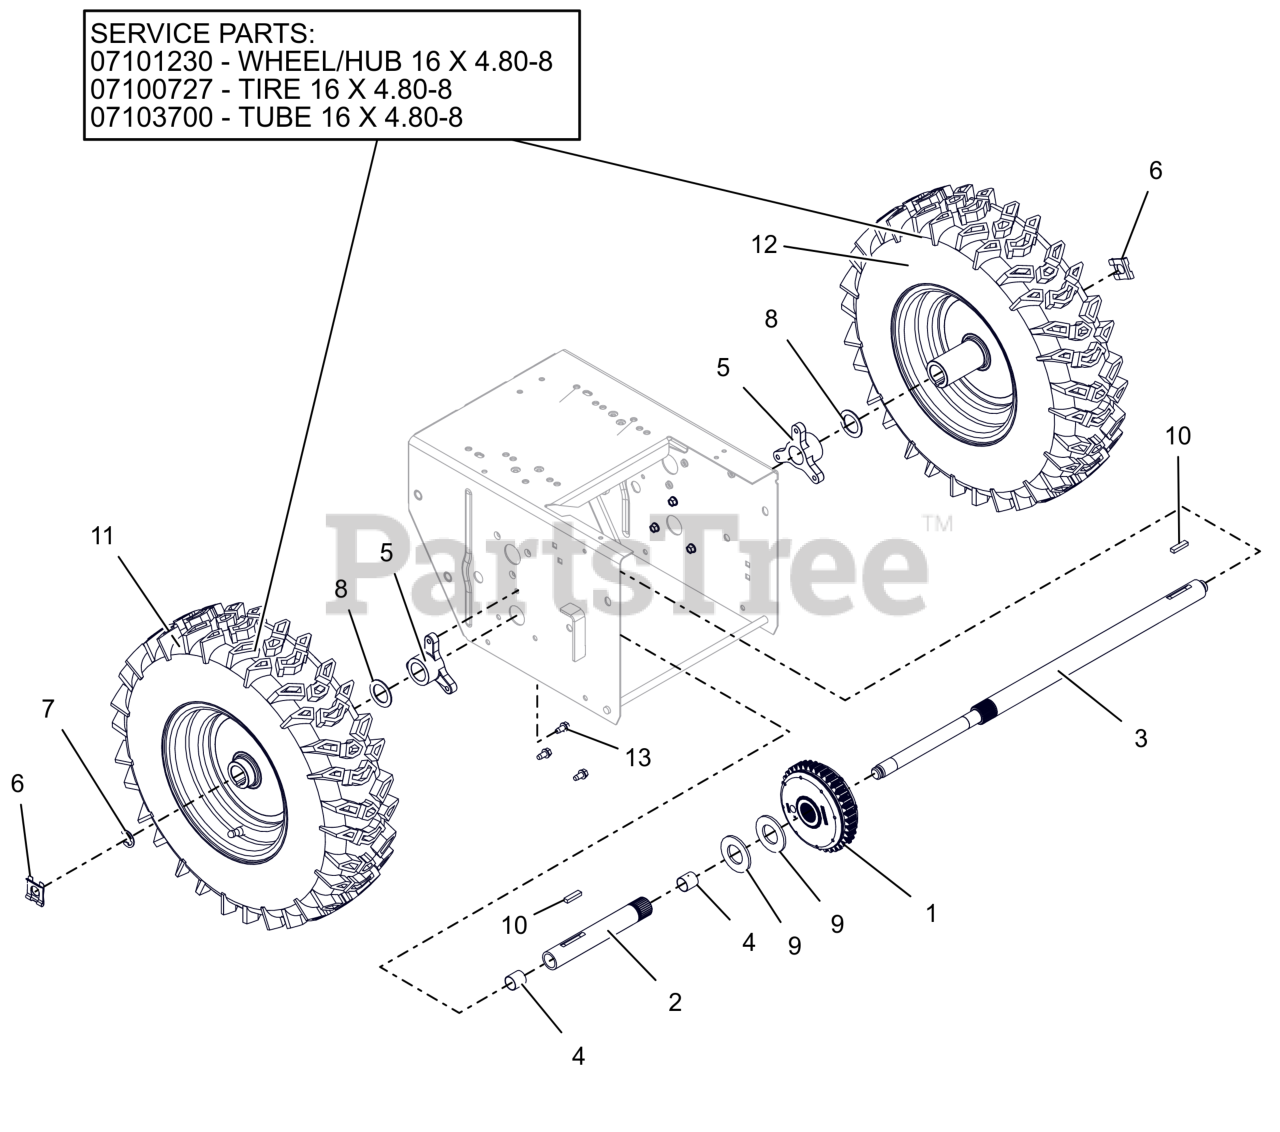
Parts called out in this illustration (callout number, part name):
1	DIFFERENTIAL, AUTOMATIC
2	AXLE, SHORT - W/BUSHINGS
3	AXLE,LONG-DELUXE AUTO DIFF
4	BSHG-SLV .706X.764X.75 BRZ
5	BUSHING, AXLE
6	CLIP, SNAP .625 DIA
7	RG-RTNG-EXT .625X.042
8	WSHR, FLT 1.010X1.505X.062 ZCC
9	WSHR, FLT 1.062X2.000X.134 ZCC
10	KEY-RECT .25X.188X1.00
11	TIRE/WHEEL,RH 16X4.8-8 DIFF T2
11-12	HUB, WHEEL-16X4.8-8
11-12	TIRE, 4.80-8 K478
11-12	TUBE
12	TIRE/WHEEL,LH 16X4.8-8 DIFF T2
13	SCR-TAP .25-20X.50 HWH ZCC
